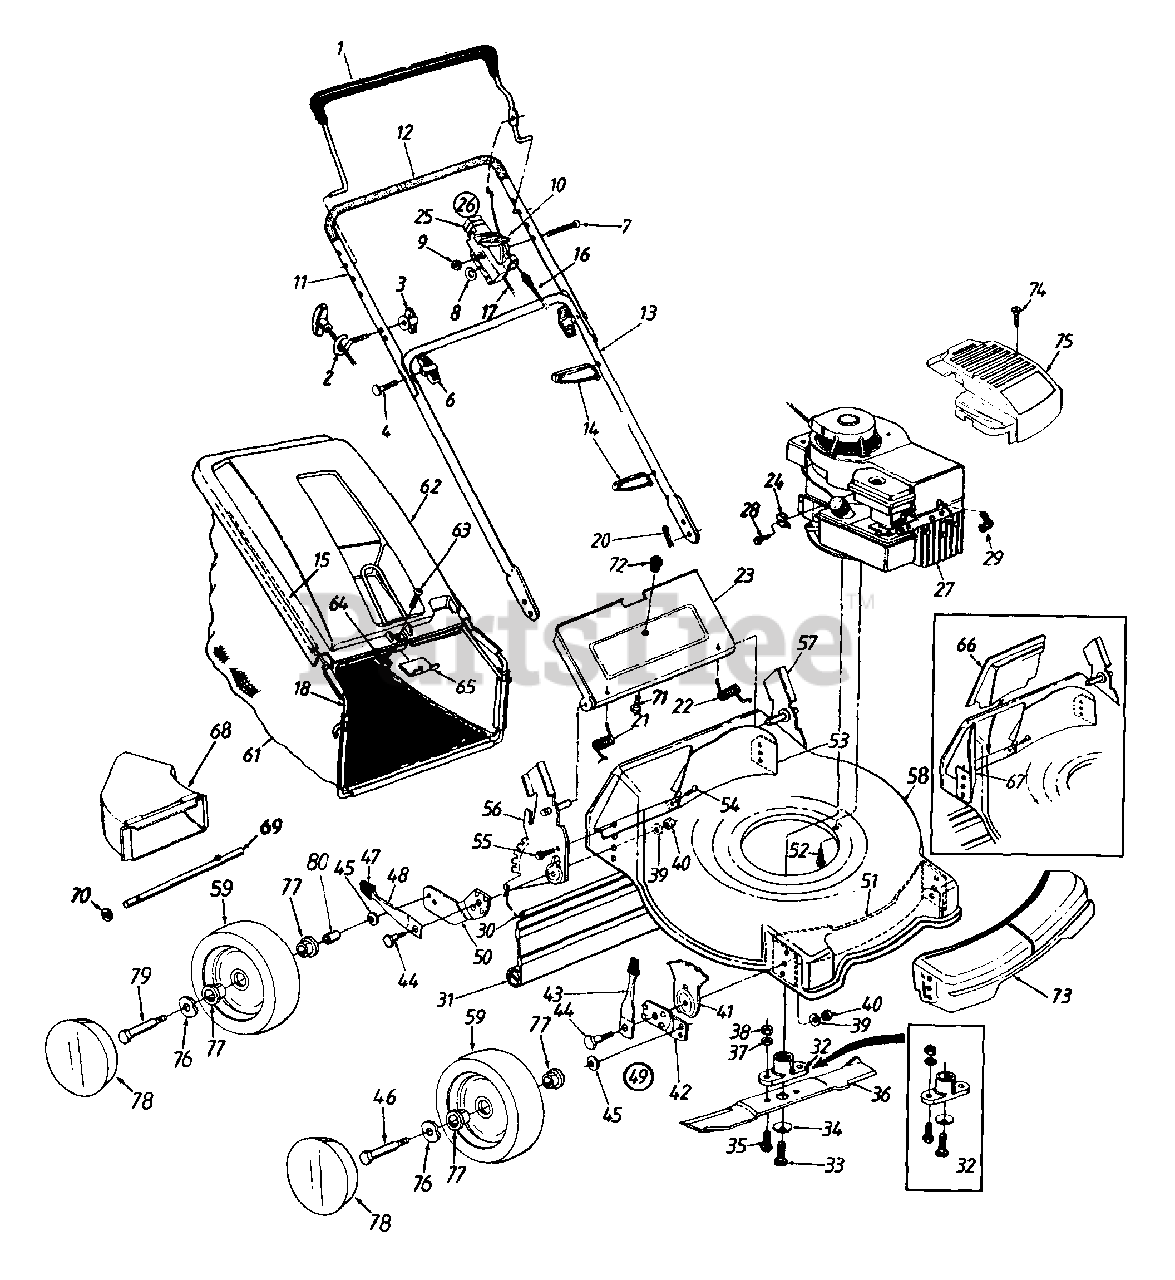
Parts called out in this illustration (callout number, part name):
1	Control Handle Ass'y.
2	Rope Guide
3	Handle Knob 1/4-20 Thd.
4	Curved Hd. Bolt 5/16-18 x 2" Lg.
6	Hand Knob
7	Oval C-Sunk Mach. Scr.
8	Spr. Wash. .66" I.D.
9	Hex L-Nut 1/4-20 Thd.
10	Throttle Lever
11	Upper Handle
12	Foam Grip
14	Cable Tie
15	Rear Catcher Frame
16	Control Cable - 36"
17	Throttle Control Wire - 55"
18	Front Catcher Frame
20	Int. Cotter Pin 5/16" Dia.
21	Door Spring - R.H.
22	Door Spring - L.H.
25	Throttle Body
26	Throttle Box Comp.
27	Engine
28	Hex Wash. Hd. Scr. #10-32 x .62" Lg.
29	Spark Plug Boot
30	Wire Rod
31	Rear Flap
32	Blade Adapter Kit
33	Hex Bolt 3/8-24 x 1.5" Lg.
34	Bell-Wash. .39" I.D.
35	Hex Bolt 3/8-24 x 1" Lg.
36	21" Mulching Blade
37	L-Wash. 3/8" I.D.
38	Hex Nut 3/8-24 Thd.
39	Bell-Wash. .39" I.D. x 1.38"
40	Hex Nut 3/8-16 Thd.
41	Height Adj. Plate
43	Spring Lever Ass'y. w/Knob
44	Shld. Bolt .5" Dia. x .357"
45	Bell-Wash. .38" I.D. x .88" O.D.
46	Front Axle Bolt
47	Spring Lever Knob
48	Spring Lever
49	Height Adj. Ass'y. Comp. - R.H.
50	Pivot Bar
51	Front Baffle
52	Hex L-Wash. Hd. Scr. 3/8-16 x 1" Lg.
53	Rear Baffle
54	Torx Mach. AB-Tap Scr. 1/4 x .62" Lg.
55	Hex L-Wash. Hd. AB-Tap Scr. 1/4 x .62" Lg.
56	Handle Brkt. Ass'y. - R.H.
57	Handle Brkt. Ass'y. - L.H.
61	Grass Bag
62	Hard Top Cover
63	Pan Hd. Mach. Scr. 1/4-20 x .5" Lg.
64	Hex Nylon L-Nut 1/4-20 Thd.
65	Mounting Bracket
66	Mulching Baffle Plug
67	Mulching Baffle - R.R.
68	Deflector
69	Rod
70	Push Speed Nut
71	Truss Scr. #10-24 x .38" Lg.
73	Deck Shroud
74	Hi-Lo Scr. #10 x 1.25" Lg.
75	XTL Grey Shroud
76	Wave Washer
77	Ball Bearings
78	Hub Cap
79	Rear Axle Bolt
80	Spacer
